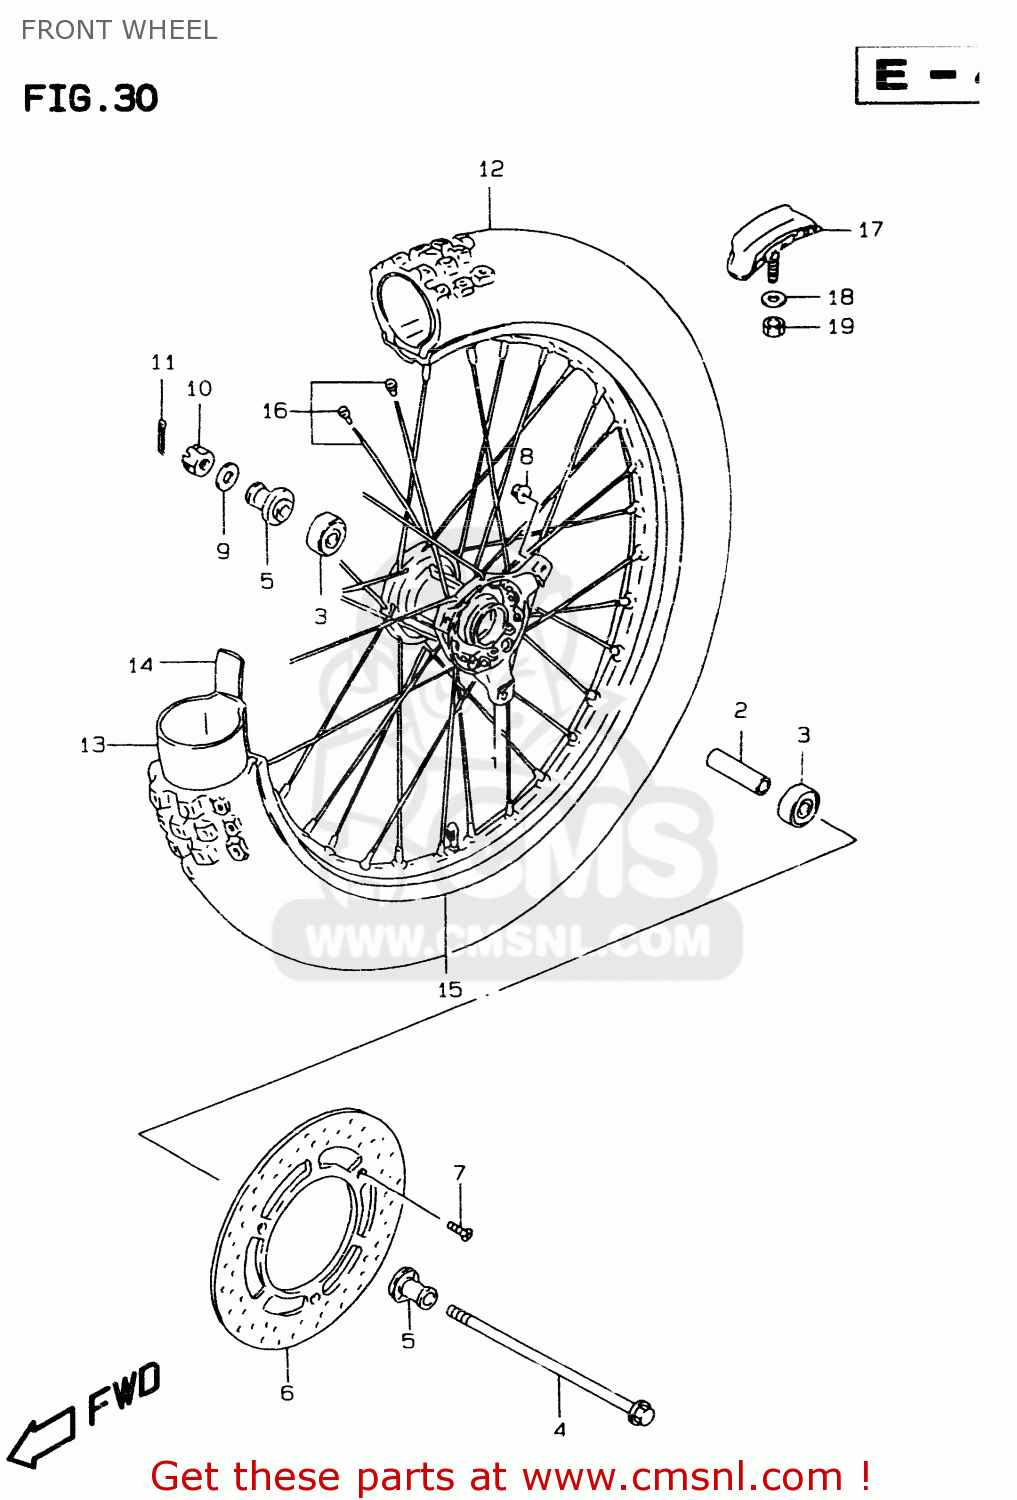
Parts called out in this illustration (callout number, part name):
1	HUB,FR WHEEL
2	SPACER,FR HUB BEARING
3	BEARING (12X32X10)
4	AXLE,FR
5	SPACER,FR AXLE
6	DISC,FRONT BRAKE
7	SCREW(6X22)
8	NUT
9	WASHER
10	NUT,M12X1.25X1
11	PIN 20X20
12	TIRE,FRONT 70/100-17
13	TUBE ASSEMBLY,WHEEL,INNER
14	PROTECTOR,WHEEL,INNER
15	RIM,FR WHEEL(1.40X17)
16	SPOKE SET,FR WHEEL
17	STOPPER,BEAD
18	WASHER
19	NUT
